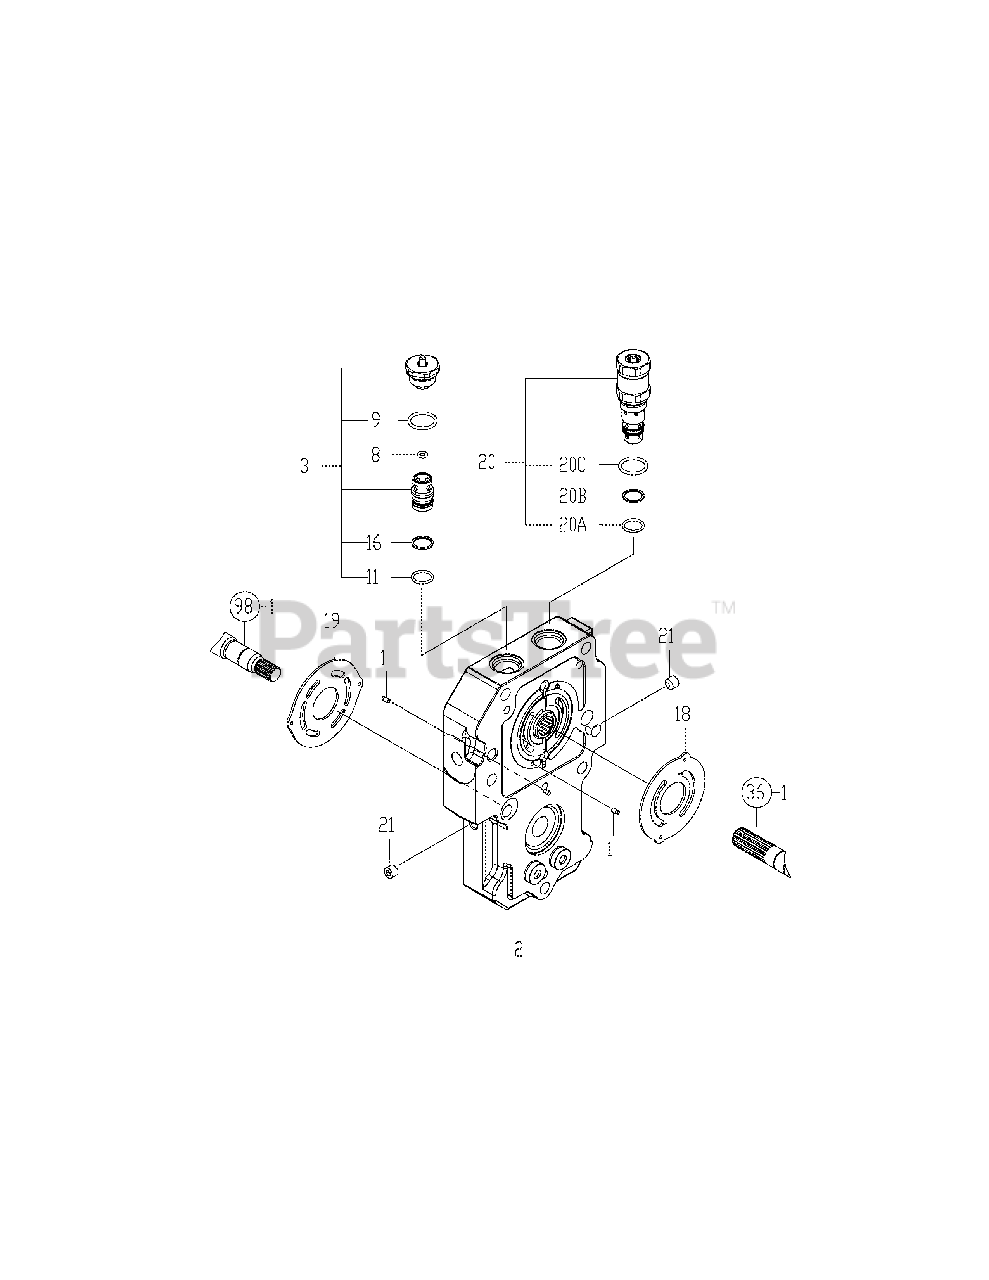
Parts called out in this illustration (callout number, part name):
1	Pin, Knock 3.5
2	Center Case K93 Cmp
3	Check Valve (R Cmp
8	Packing, P 5.0
9	Packing, P 20.0
16	Ring, Back Up 18
20	Releaf Assy, Tow 25
20B	Ring, Back Up 18
20C	Packing, P 20.0
